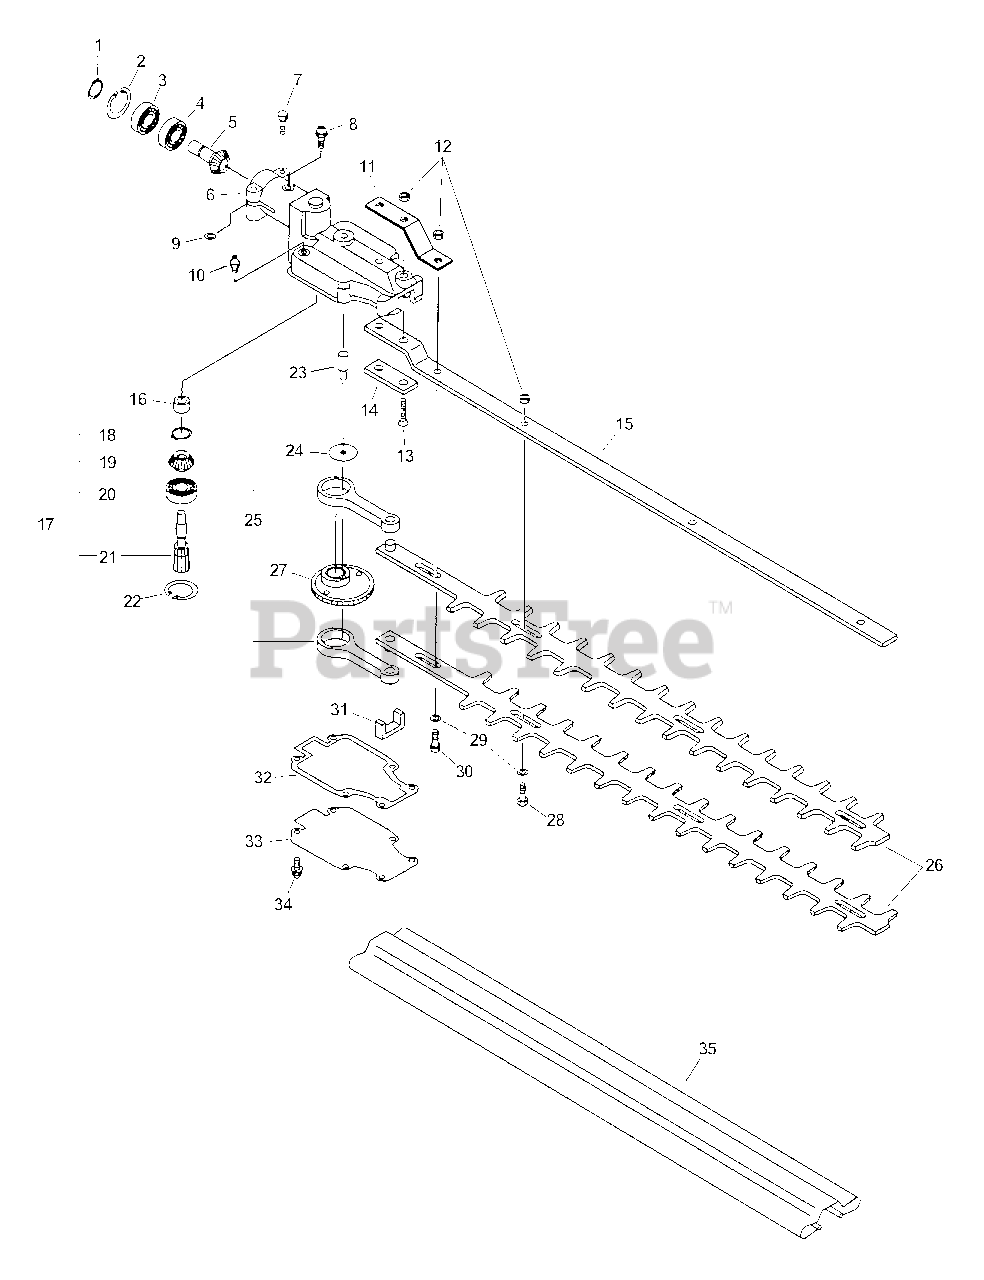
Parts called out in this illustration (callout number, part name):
1	RING, RETAINING - 12
2	RING, RETAINING - 24
3	BEARING, BALL - 6901Z
4	BEARING, BALL - 6901
5	GEAR
6	CASE, GEAR
7	SCREW - 5X28
8	SCREW - 5X12
10	FITTING, GREASE
11	BRACKET
12	LOCKNUT - 6
13	SCREW - 6X35
15	SUPPORT, BLADE - 20" (50cm)
16	BEARING, NEEDLE
17	SPUR GEAR ASSY
18	RING, RETAINING
19	GEAR - BEVEL -- DRIVEN
20	BEARING, BALL - 6901
21	GEAR - SHAFT
22	RING, RETAINING - 24
23	DRIVESHAFT
25	ROD, CONNECTING
26	BLADE - 20" (50cm)
27	GEAR - DRIVE
29	WASHER - 6
31	SEAL, FELT
32	GASKET, GEAR CASE
33	LID, GEAR CASE
34	SCREW - 4X12
35	COVER, BLADE
